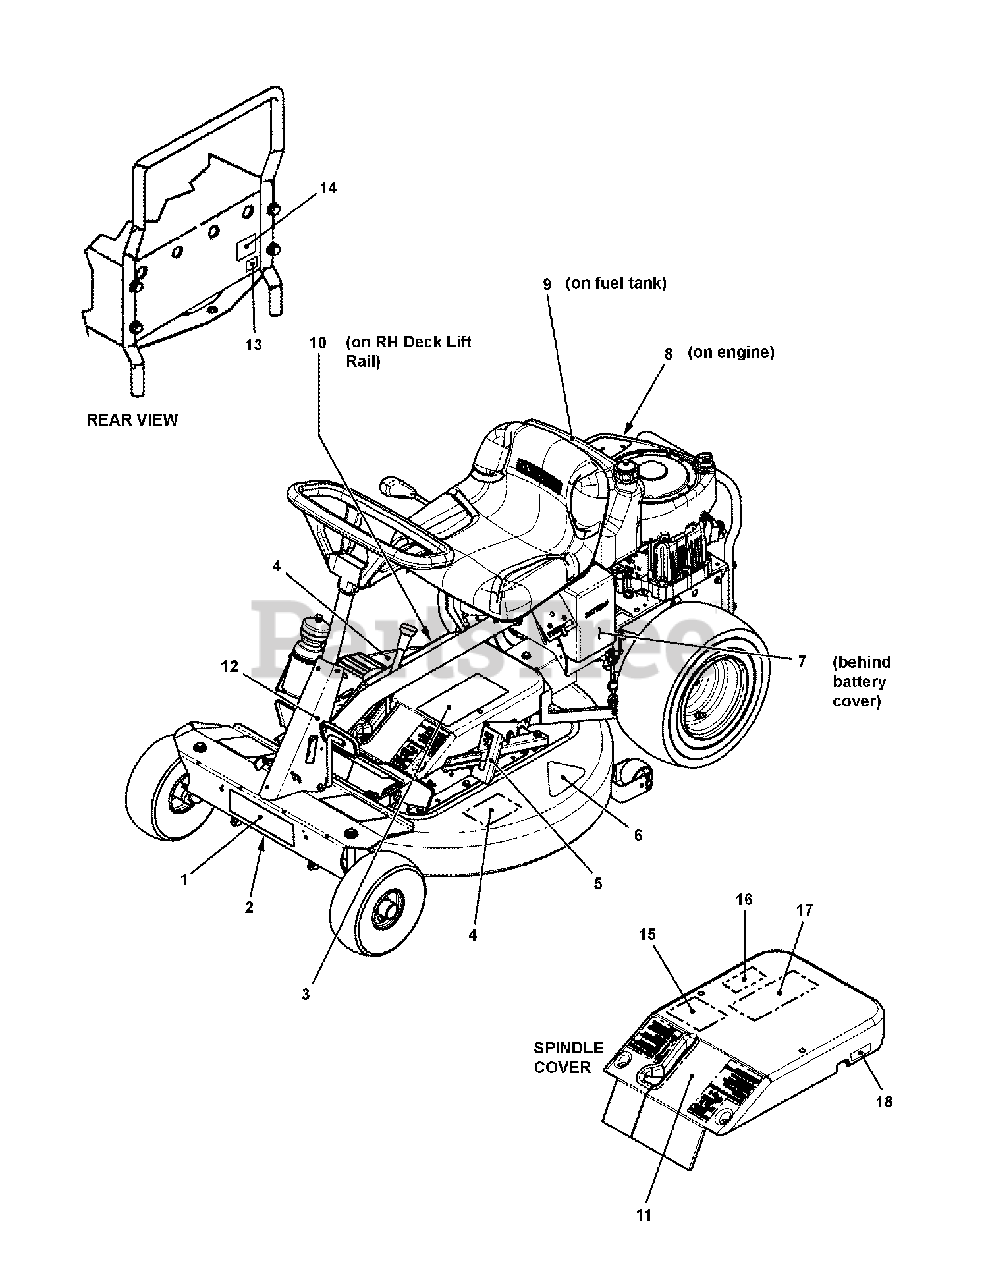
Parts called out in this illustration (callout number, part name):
1	DECAL, SNAPPER
2	DECAL, Battery Storage
3	DECAL, Safety Instructions (French/German)
3	DECAL, Safety Instructions (English/Dutch)
3	DECAL, 8-Panel Symbols, Euro RER
3	DECAL, Safety Instructions (Spanish/Italian)
4	DECAL, Deck Symbols- International
5	DECAL, Height of Cut
6	DECAL, 33 Inch (Hi-Vac)
7	DECAL, Battery Caution, Multi-Language
7	DECAL, Battery Orientation, Euro RER
8	DECAL, Back-Up Recoil (33" Kohler Engine Models)
8	DECAL, OHV (33" Kohler Engine Models)
8	DECAL, Engine, B&S E10 Powerbuilt
9	DECAL, Caution, Fuel Leakage (English)
9	DECAL, Caution, Fuel Leakage (Dutch)
9	DECAL, Caution, Fuel Leakage (French)
9	DECAL, Caution, Fuel Leakage (German)
9	DECAL, Caution, Fuel Leakage (Symbols)
9	DECAL, Caution, Fuel Leakage (Italian)
9	DECAL, Caution, Fuel Leakage (Spanish)
10	DECAL, Deflector, French/German
10	DECAL, Deflector Caution (English/Dutch)
10	DECAL, Blade Caution, Euro RER
11	DECAL, Brake Operation (German)
11	DECAL, Brake Operation (French)
11	DECAL, Brake Operation (Dutch)
11	DECAL, Brake Operation (Italian)
11	DECAL, Brake Operation (Spanish)
12	DECAL, Clutch Brake
13	DECAL, Euro Community (CE)
14	DECAL, European Noise Control (100 dB)
14	DECAL, European Noise Control (98 dB)
15	DECAL, No Mow in Reverse (Euro)
16	DECAL, Deck/Chute International Warning
17	DECAL, Service Parts, Euro
18	DECAL, Remove Battery, Symbols, Euro
